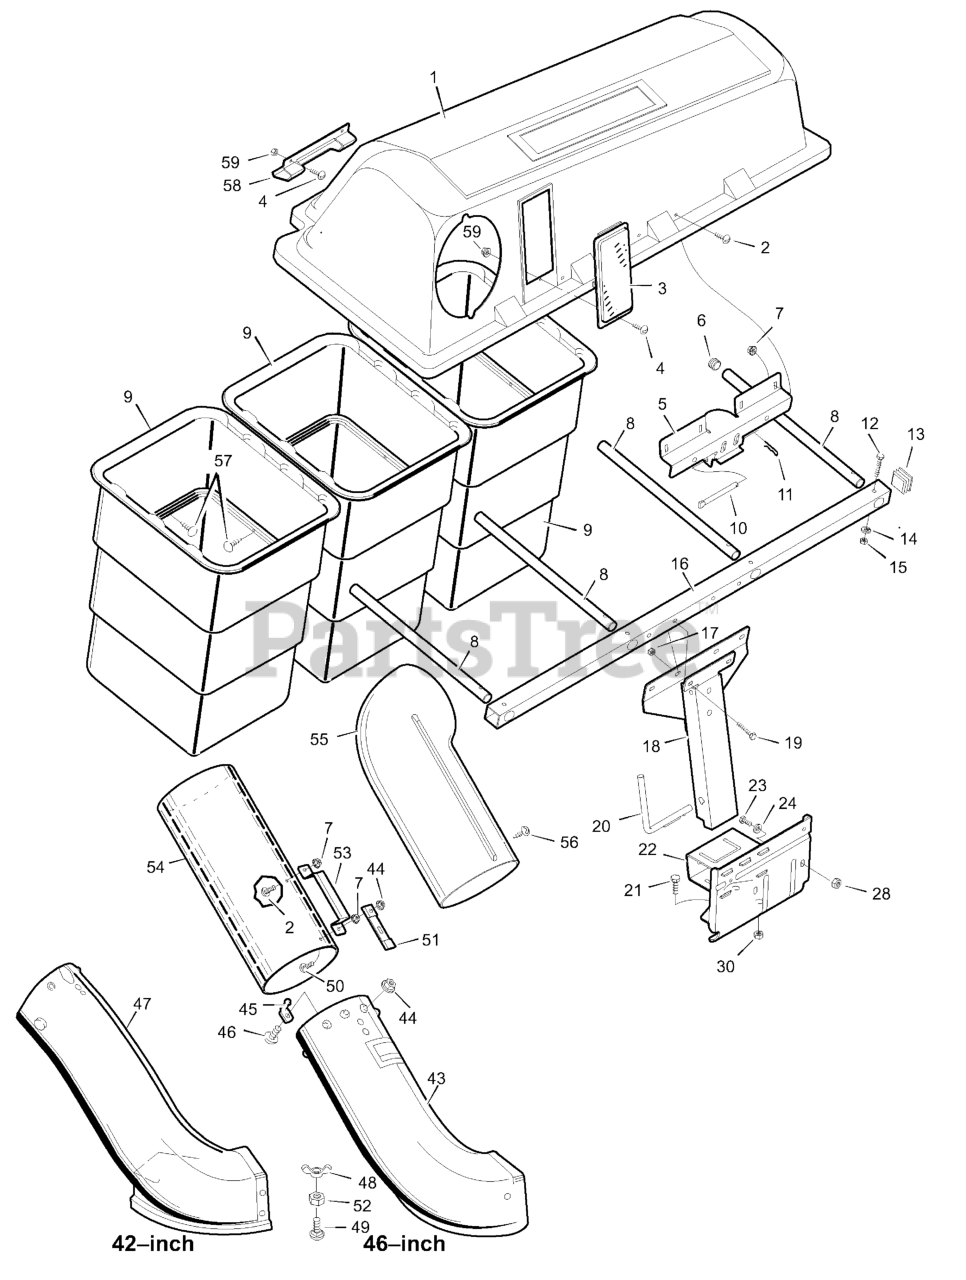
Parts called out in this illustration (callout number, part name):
1	Cover, Bagger
5	Hinge, Bracket
7	Nut, Hex
8	Tube, Container
9	Container
10	Pin, Cover Hinge
11	Pin, Hair
13	Plug
14	Lockwasher
16	Tube, Support
17	Nut
18	Assembly, Channel
20	Pin, Channel Mount
21	Bolt, Hex
22	Assembly, Bagger Mount
23	Bolt, Hex
28	Nut, Super Flange
30	Nut, Hex
43	Extension, Chute
44	Locknut, Flange
45	Pin, Latch
46	Bolt, Carriage
47	Extension, Chute
48	Wingnut
49	Bolt, Carriage
51	Latch, Rubber
53	HANDLE, Connect Tube
54	Tube, Connecting
57	Fastener, Panel
58	Handle, Plastic
59	Nut, Hex
